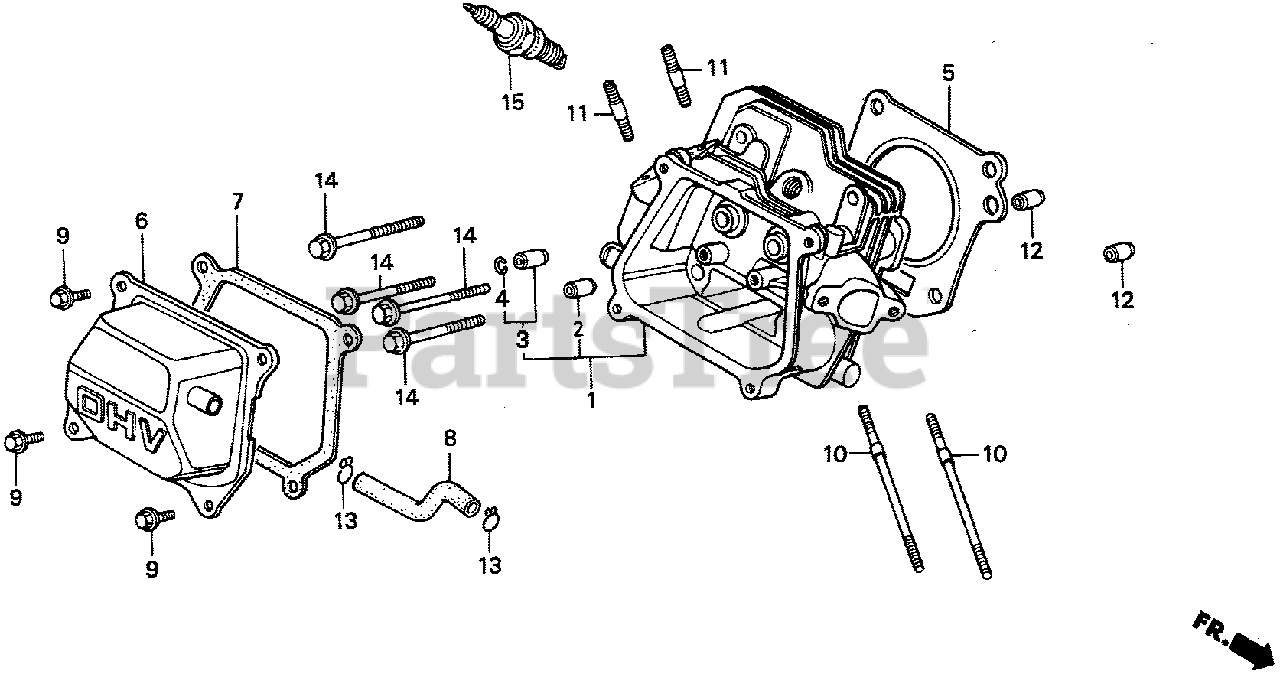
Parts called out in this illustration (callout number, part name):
1	CYLINDER HEAD
2	GUIDE, VALVE (OS)
3	GUIDE, EX. VALVE (OS)
4	CLIP, VALVE GUIDE
5	GASKET, CYLINDER HEAD
6	COVER, HEAD
7	GASKET, CYLINDER HEAD COVER
8	TUBE, BREATHER
9	BOLT, FLANGE (6X12) (CT200)
9	BOLT, FLANGE (6X13)
10	BOLT, STUD (6X109)
11	BOLT, STUD (8X32)
12	PIN A, DOWEL (10X16)
14	BOLT, FLANGE (8X55)
15	SPARK PLUG (BPR5ES) (NGK)
15	SPARK PLUG (W16EPR-U) (DENSO)
15	SPARK PLUG (BPR6ES) (NGK)
15	SPARK PLUG (W20EPR-U) (DENSO)
